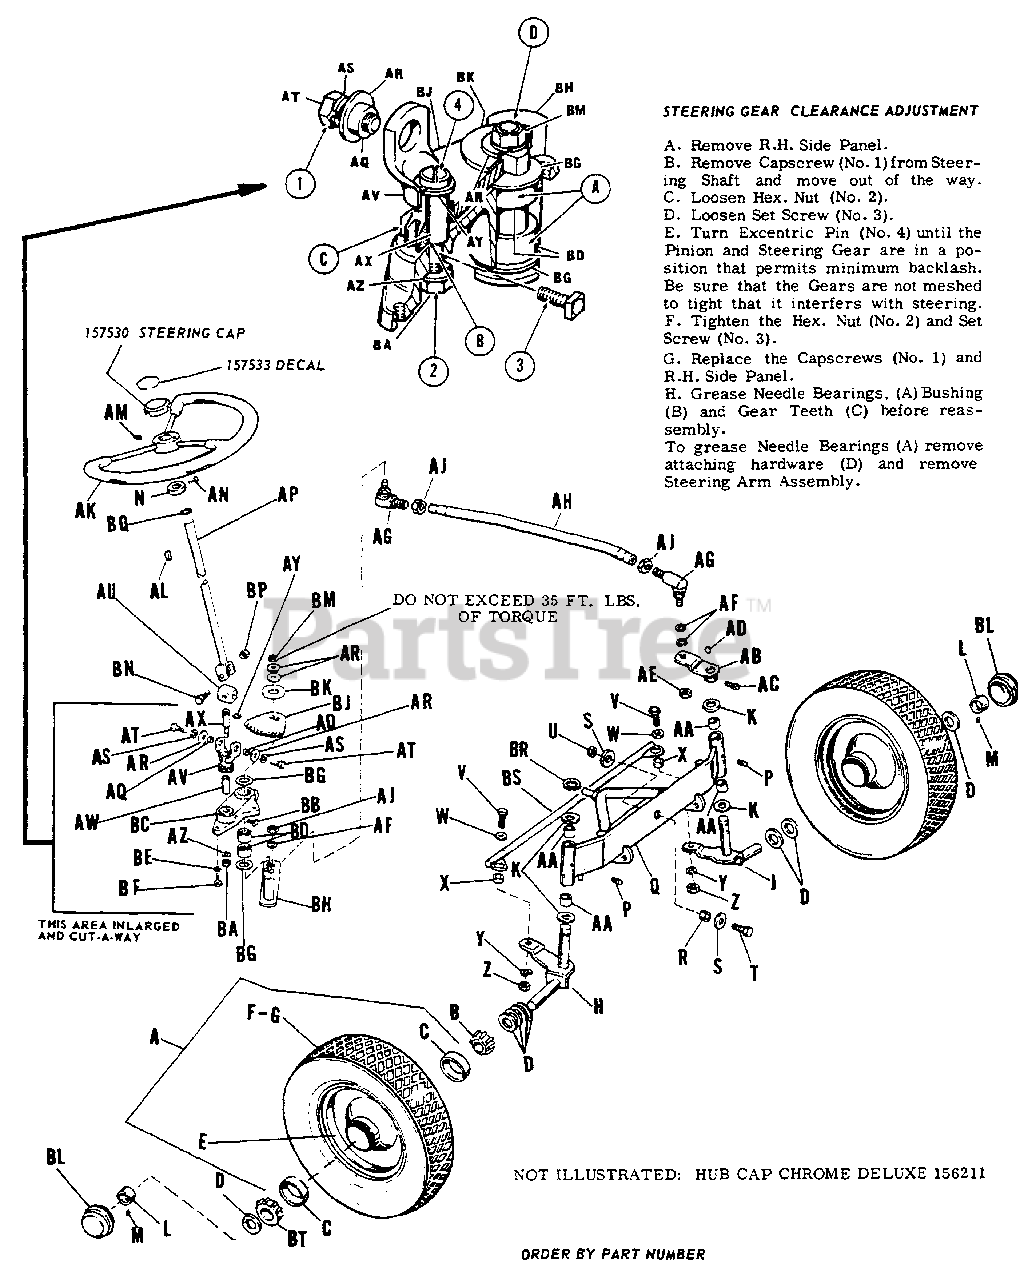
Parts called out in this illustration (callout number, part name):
A	Wheel and Tire Assembly (157505 on 399 & 400)
B	Bearing Cone, w/seal
C	Bearing Cup
E	Wheel w/Bearing Cup (157506 on 399 & 400)
F	Tire 4.80/4.00 (157490 on 399 & 400)
G	Tube, 4.00-8 (164247 on 399 & 400)
H	Spindle Assembly, R.H. (157294)
J	Spindle Assembly, L.H. (157291)
L	Set Collar
M	Cup Point Socket Head Set Screw, 5/16"-18 x 5/16" lg.
N	Set Collar
P	Grease Fitting (727002)
Q	Axle Assembly, Front (154255)
S	Plain Washer, 1/2"
T	Hex. Cap Screw, 1/2"-13 x 1" lg.
U	Full Lock Hex. Nut, 1/2"-13
V	Hex. Cap Screw, 3/8"-16 x 1-1/4" lg.
W	Plain Washer, 3/8"
Y	Lock Washer, 3/8"
Z	Full Hex. Nut, 3/8"-16
AB	Arm Assembly, Steering, L.H. (154172)
AC	Screw, Set, Sq. Hd. Cup Pt, 5/16"-18 x 1/2" lg.
AD	Drive Shaft Key (725504)
AE	Full Hex Lock Nut 1/2"-20 (717528)
AF	Lock Washer, 1/2"
AG	Ball Joint (164272)
AH	Tie Rod (164271)
AJ	Nut, 1/2"-20 N.F.
AK	Steering Wheel (157702 on 568 & 569)
AL	Woodruff Key, #9
AM	Socket Head Cup Point Set Screw, 5/16"-18 x 5/16" lg.
AN	Socket Hd. Set Screw, 5/16"-18 x 1/4" lg.
AP	Steering Shaft Assembly
AR	Plain Washer, 3/8"
AS	Lock Washer, 3/8"
AT	Hex Cap Screw, 3/8"-16 x 3/4" lg.
AU	Universal Joint Pin
AV	Bushing Assembly
AX	Pin Eccentric
AY	Retainer Ring
AZ	Lock Washer, 3/8"
BA	Full Hex. Nut, 3/8"-16
BB	Sq. Hd. Set Screw, 1/4"-20 x 3/4" lg.
BC	Steering Bracket
BD	Needle Bearing
BE	Lock Washer, 5/16"
BF	Hex. Cap Screw, 5/16"-18 x 5/8"
BH	Steering Arm Assembly (164263)
BJ	Gear Steering (164235)
BK	Arbor Washer
BL	Hub Cap
BM	Gripco Center Lock 7/16"-14
BN	Hex Cap Screw,
BP	Full Hex. Nut, 5/16"-18
BQ	Snap Ring (154264)
BR	Retaining Ring
BS	Drag Link Assembly
BT	Bearing Cone w/o Seal
